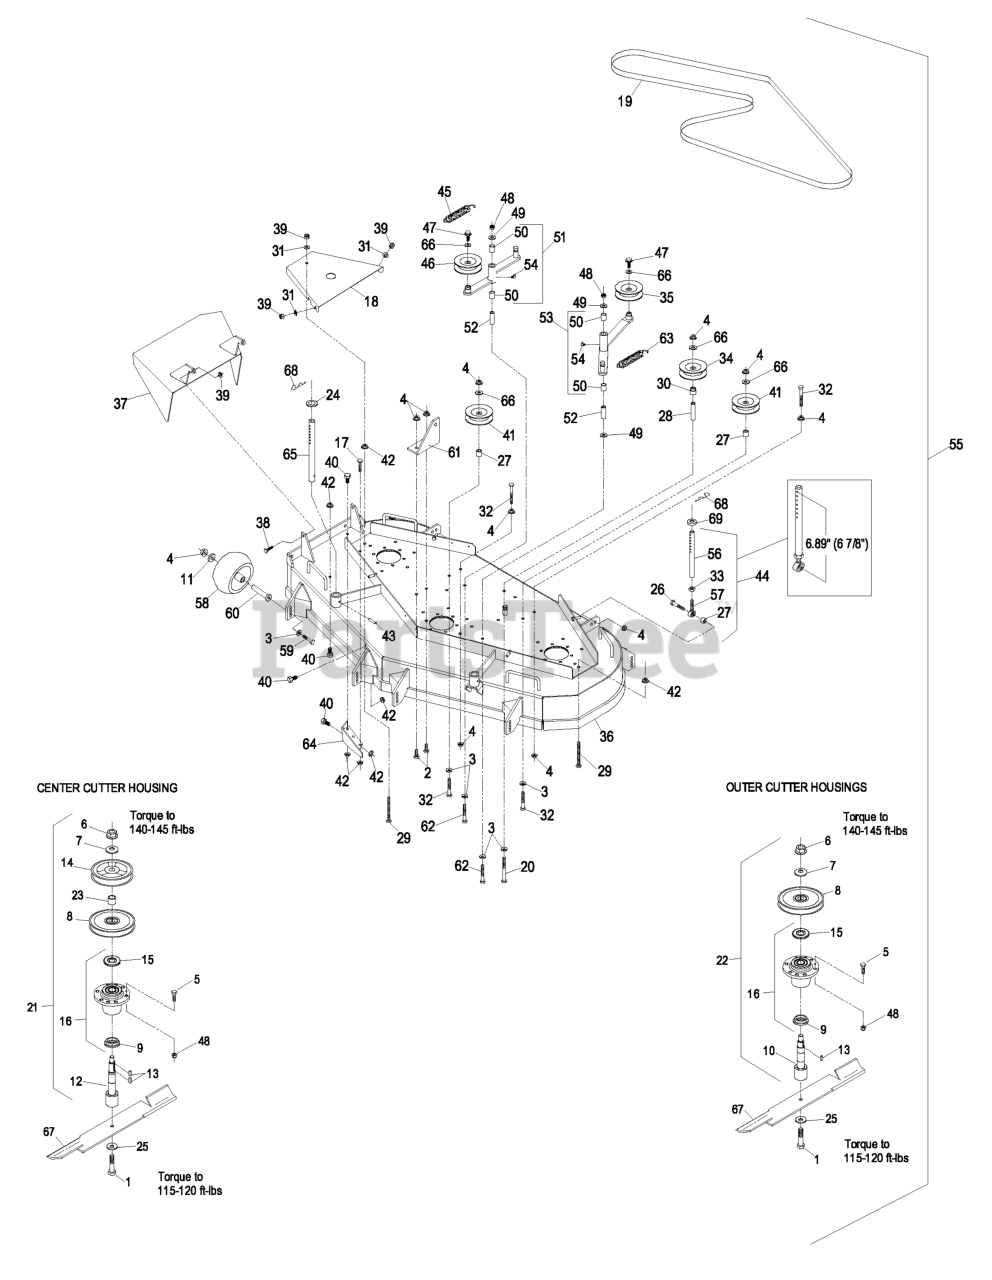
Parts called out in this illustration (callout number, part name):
1	SCREW-CAP
2	SCREW-HH
3	WASHER-BELLEVILLE
4	NUT-HHF, WHIZ
5	SCREW-HH
8	SHEAVE,BLADE DRIVE 6.30
9	SPACER-GUARD, BOTTOM
10	SPINDLE,SHORT
12	SPINDLE,LONG
14	SHEAVE,MOWER DRIVE
15	GUARD-BEARING, TOP
17	SCREW-HH
18	SHIELD,BELT SIDE FMD524
19	BELT,BLADE DRIVE FMD524
20	SCREW-HH
23	SPACER,TUBE
24	SPACER-DECK SUPPORT
25	WASHER-BLADE BOLT, HEAVY
26	SCREW-HH
28	SPACER-ANCHOR, CLUTCH
29	BOLT,TAP HH
30	BUSHING,IDLER
31	WASHER-FLAT
32	BOLT-CARR
33	NUT-HEX
34	PULLEY-IDLER
35	PULLEY-IDLER
38	SCREW-HH
39	NUT-LOCK, NI
40	SCREW-HH
41	IDLER,PULLEY
45	SPRING-EXTENSION
46	IDLER,PULLEY
47	SCREW-HHF
48	NUT-LOCK, NI
49	WASHER-FLAT
50	SLEEVE-BEARING
51	ASM,IDLER ARM
52	BUSHING-PIVOT, IDLER
53	ASM,IDLER ARM
54	FITTING-GREASE, 90 DEG
55	Complete Deck Assembly
56	LINK,SUPPORT
57	BALLJOINT
58	ROLLER-SCALP, ANTI
59	SCREW-HH
60	BUSHING-ROLLER
61	BRACKET,SPRING ANCHOR
62	SCREW-HH
63	SPRING-EXTENSION
64	WLD,BAFFLE DISCHARGE
65	ROD,DECK SUPPORT
66	WASHER-FLAT
68	PIN,HAIR COTTER
